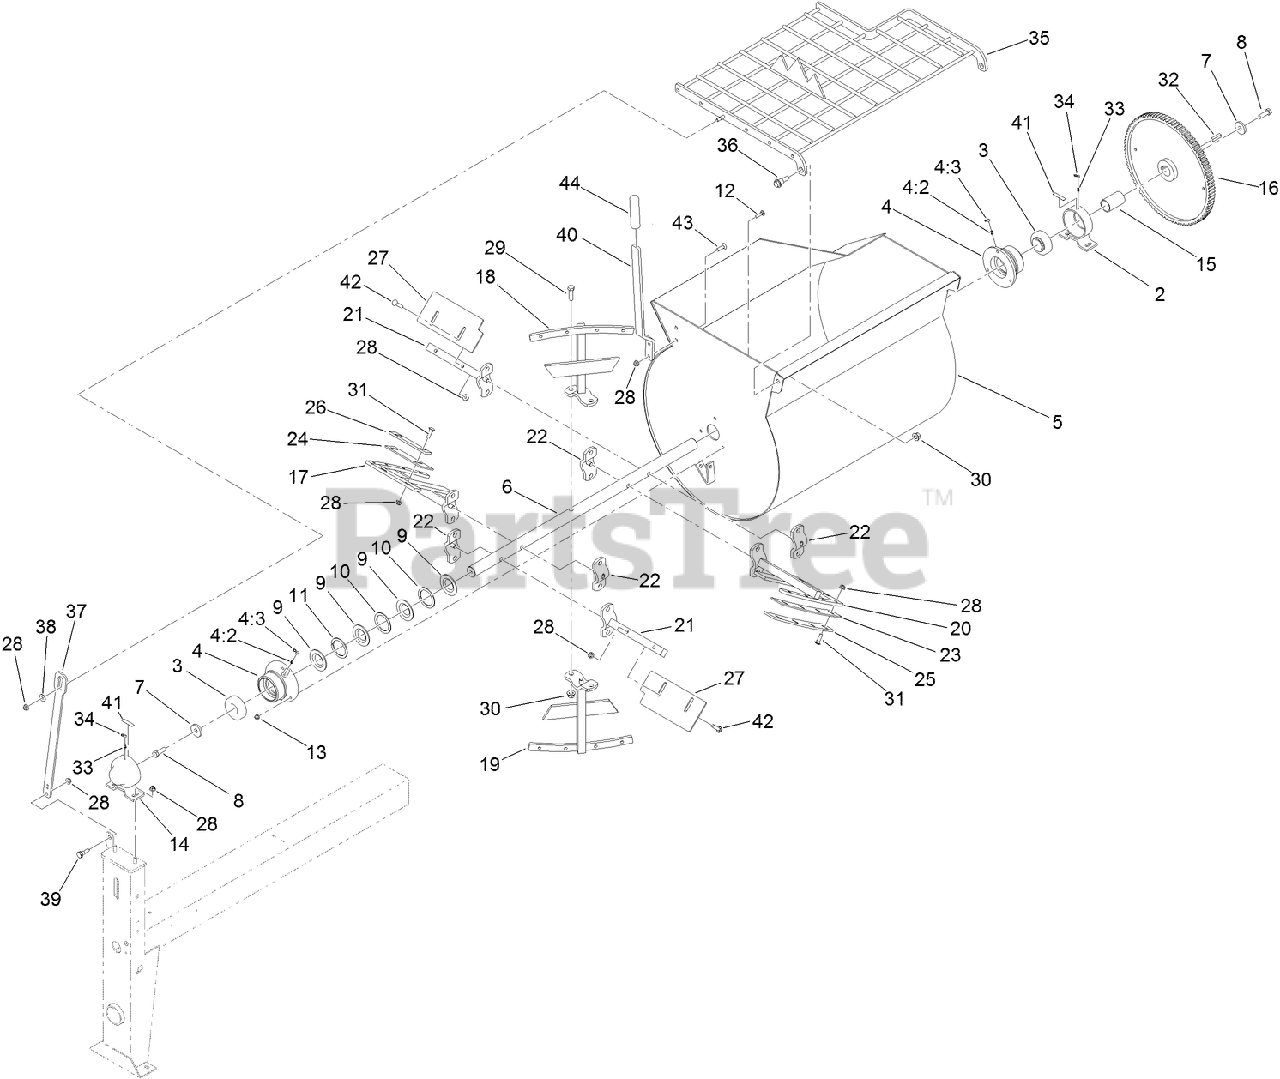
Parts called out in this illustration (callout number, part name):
2	TRUNNION
3	BEARING-BALL
4	KIT-HOUSING, BEARING
4:2	FITTING-GREASE
4:3	CAP-PLUG
6	SHAFT-PADDLE
7	WASHER-FLAT
8	SCREW-HH
9	SEAL-DRUM
10	WASHER-FLAT
11	WASHER-SPLIT
12	SCREW-CARR
13	NUT-HF, NI
14	TRUNNION-CAPPED
15	SPACER-SHAFT
16	GEAR-94 TEETH
17	PADDLE-LEADING
18	PADDLE-MID
19	PADDLE-MID
20	PADDLE-TRAILING
21	PADDLE-PUSHER
23	PADDLE-RUBBER, TOP
24	PADDLE-RUBBER, MIXER END
25	BAR-BACKER, TOP
26	BAR-BACKER, END
27	BAR-BACKER, PUSHER END
28	NUT-HF, NI
29	SCREW-HH
30	NUT-LOCK
31	BOLT-CARR
32	KEY-SQUARE
33	FITTING-GREASE
34	CAP-PLUG
35	GUARD-DRUM, 85MM
36	SCREW-SHOULDER, HHF
37	ARM-LIFT, GRATE
38	WASHER-HARDENED
39	BOLT-SHOULDER
40	HANDLE-DUMP
41	DECAL-GREASE
42	SCREW-CARR
43	SCREW-CARR
44	GRIP-FOAM
